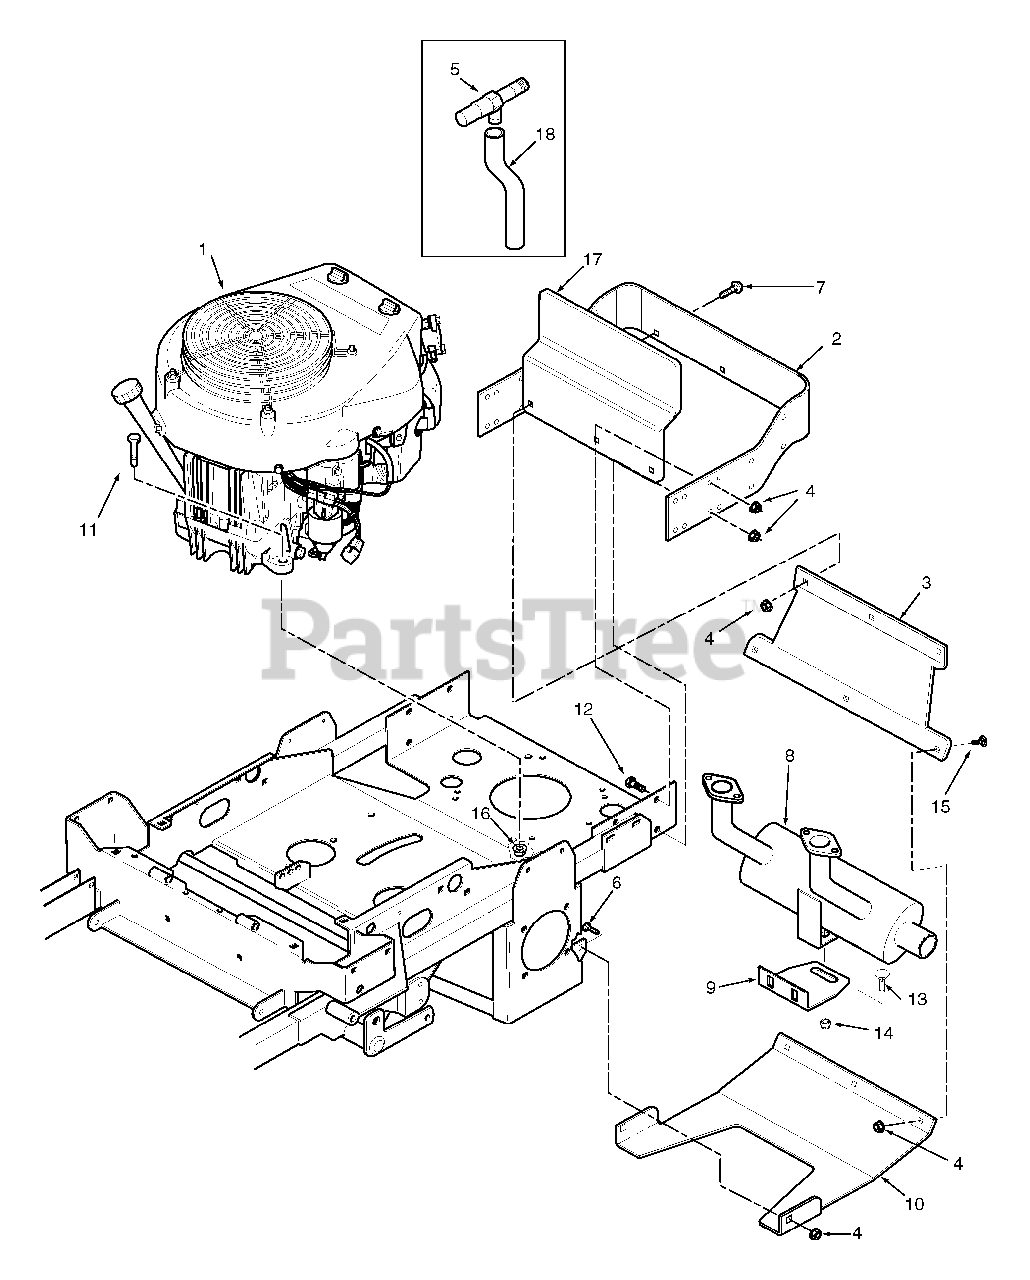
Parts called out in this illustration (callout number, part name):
1	Engine, Briggs & Stratton 26hp ELS
2	Bumper, Rear
3	Shield, Rear
4	Nut, Serr. Flange 3/8-16
5	Extension, Oil Drain 3.3"
6	Bolt, Carr. 3/8-16 x 1"
7	Bolt, 3/8-16 x 1" Torx
8	Muffler
9	Bracket, Muffler
10	Plate, Skid
11	Bolt, Hex Head 5/16-18 x 1-1/2"
12	Bolt, Hex Head 3/8-16 x 1"
13	Bolt, Hex Head 5/16-18 x 3/4"
14	Nut, Serr. Flange 5/16-18
15	Bolt, Carr. 3/8-16 x 3/4"
16	Nut, Serr. Flange 5/16-18
17	Guard, Carb Inlet
18	Tubing, Oil Drain 1/2" x 8"
